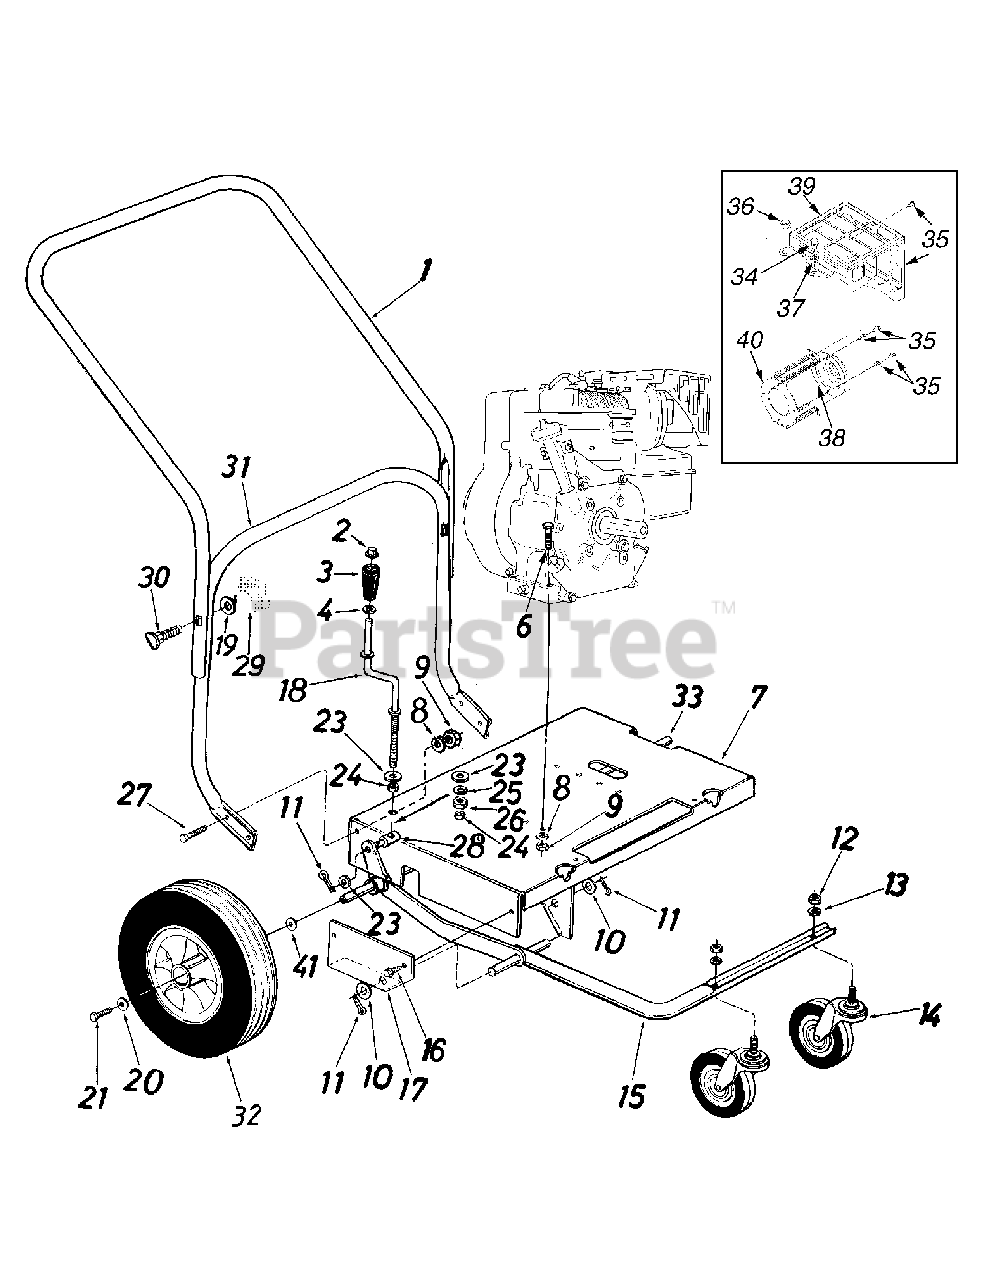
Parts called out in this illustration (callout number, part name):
2	Push Nut 3/8
3	Crank Knob
4	Flat Washer.385 ID x.62 OD
6	Hex Bolt 5/16-18 x 1.50
9	Hex Nut 5/16-18
10	Flat Washer.63 ID x 1.25
11	Cotter Pin
12	Hex Nut 1/2-13
13	Lock Washer 1/2
14	Swivel Caster Wheel 5" Dia x 1.25
19	Saddle Washer.32 ID x.93 OD
20	Flat Washer.34 ID x.87 OD
21	Hex Lock Bolt 5/16-24 x.64
23	Flat Washer.38 ID x.57 OD
24	Spacer.382 ID x.50 OD x.180Lg
25	Lock Washer 3/8 ID
26	Hex Nut 3/8-8
27	Hex Bolt 5/16-18 x.75
28	Ferrule
29	Hand Knob
30	Carriage Bolt 5/16-18 x 2.0
33	Rear Axle
34	Self Tap Screw 1/4-20 x.5
35	Screw 8-18 x.375
36	Hex Lock Nut 5/16-18
37	Lock Washer
38	Deflector
39	Muffler Guard
40	Muffler Guard Bracket
41	Flat Washer
42	Hex Lock Nut 5/16-18
